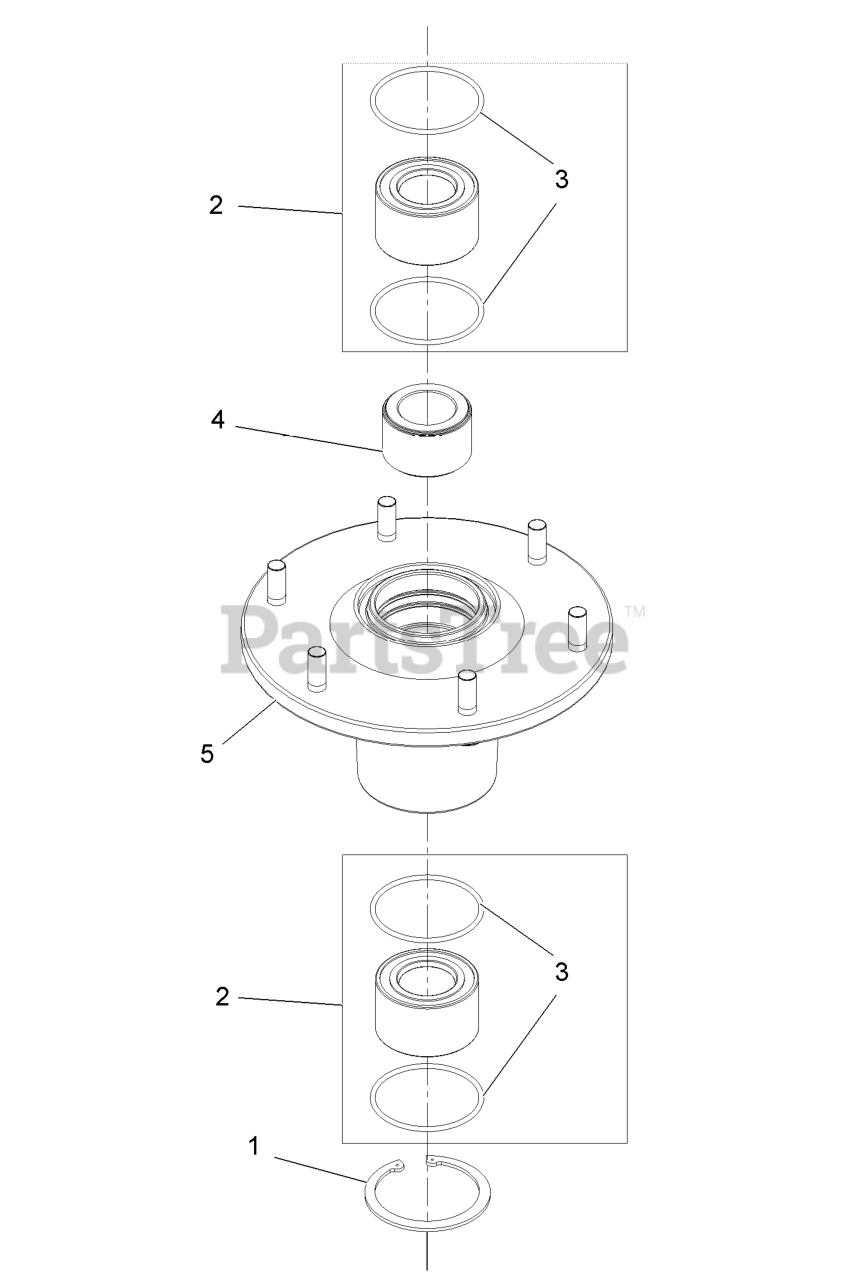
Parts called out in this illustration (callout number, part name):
1	RING-RETAINING
2	ASM, BEARING W/ORINGS
4	SPACER,BEARING
5	ASM,HOUSING W/STUDS
